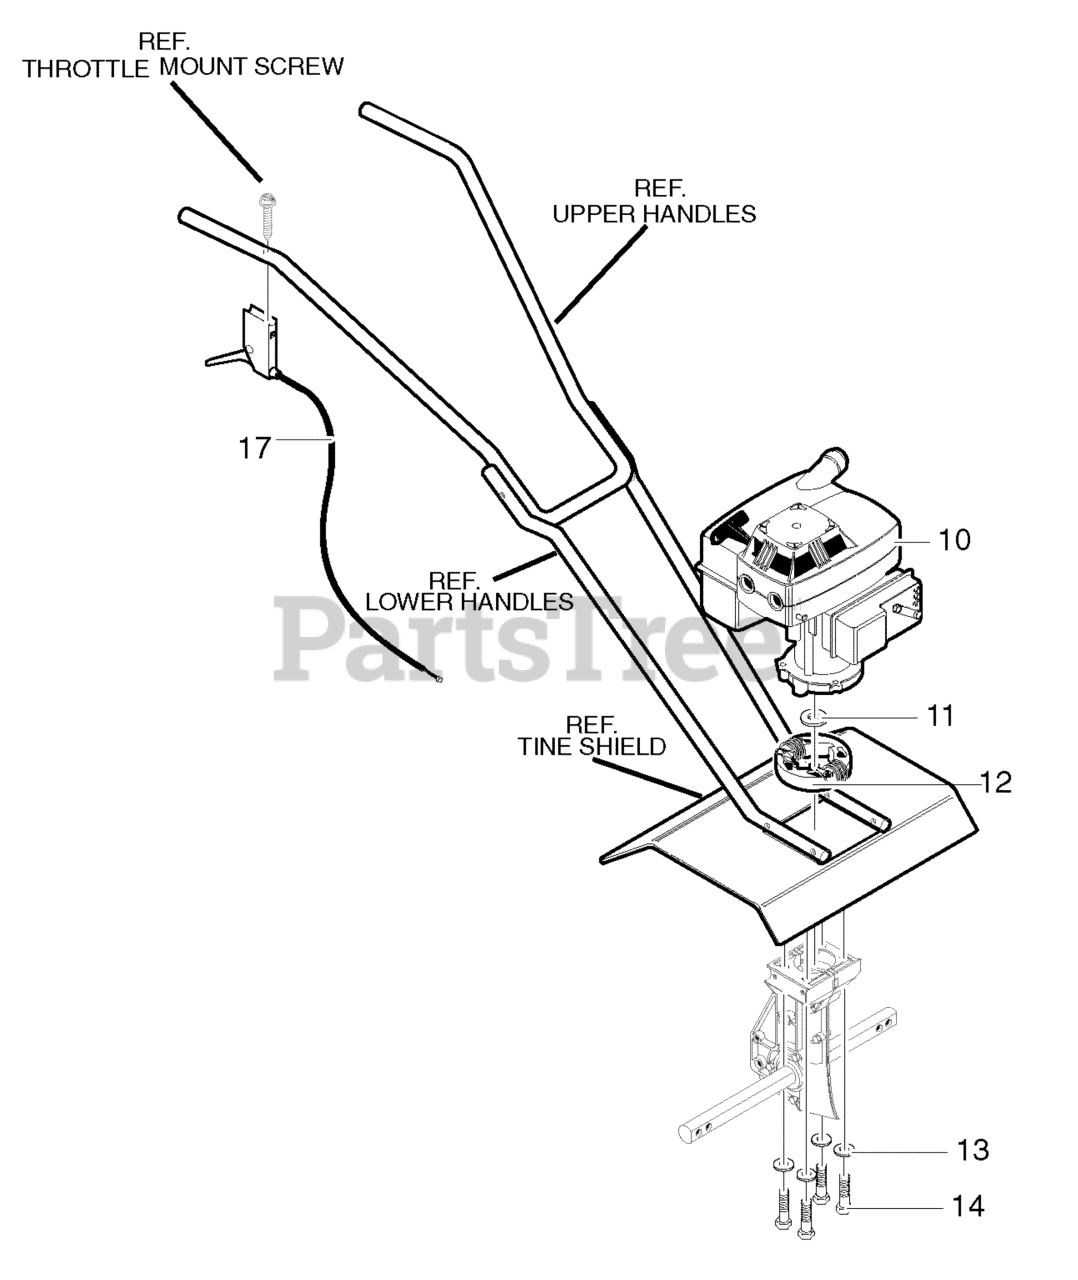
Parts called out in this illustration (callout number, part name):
10	ENGINE (2.0 HP)
11	WASHER, Flat
17	CABLE, Throttle
